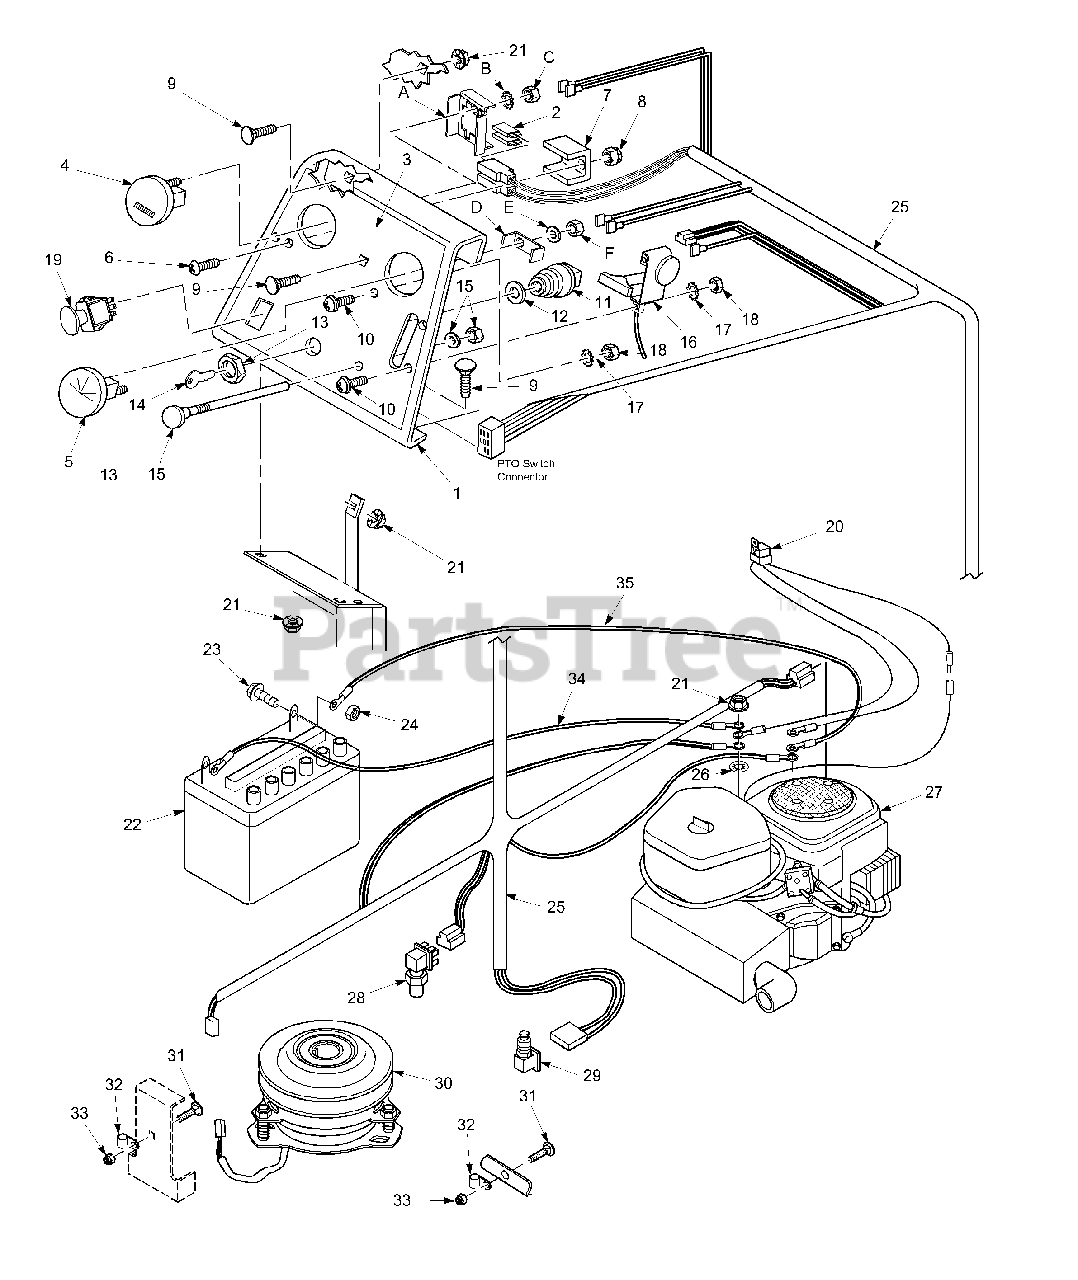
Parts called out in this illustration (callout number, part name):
1	Instrument Panel
2	Blade Fuse, 20 amp.
3	Decal, Instrument Panel
4	Hour Meter
5	Ammeter
6	Phillips Rd. Head Screw, #10-32 x 1-1/2"
7	Bracket, Fuse Holder
8	Elastic Stop Nut, #10-32
9	Carriage Bolt, 5/16-18 x 3/4"
10	Phillips Washer Head Screw, #10-32 x .50"
11	Keyswitch
12	Lockwasher, 5/8 Int. Tooth
14	Ignition Key and Ring Assy.
15	Choke Control
16	Throttle Control
17	Lockwasher, #10 Ext. Tooth
18	Hex Nut, #10-32
19	Switch, PTO
20	Wire Harness With Relay
21	Serr. Fl. HH Nut, 5/16-18
22	Battery
23	Bolt, Hex head 1/4-20 x 1/2"
24	Hex Nut 1/4-20
25	Wire Harness, STHM
26	Lockwasher 5/16 Int. Tooth
27	Engine, 23 HP Kohler CV (Spec PS-75523)
28	Switch, Parking Brake
29	Switch, Foot Safety
30	Clutch, Electric
31	Carriage Bolt, 5/16-18 x 3/4"
32	Wireloom
33	Locknut, Elastic Stop 5/16-18
34	Battery Cable, 36" Black
35	Battery Cable, 25" Red
A	Hour Meter Bracket
B	Lockwasher, #10 Ext. Tooth
D	Ammeter Bracket
E	Lockwasher, #10 Int. Tooth
